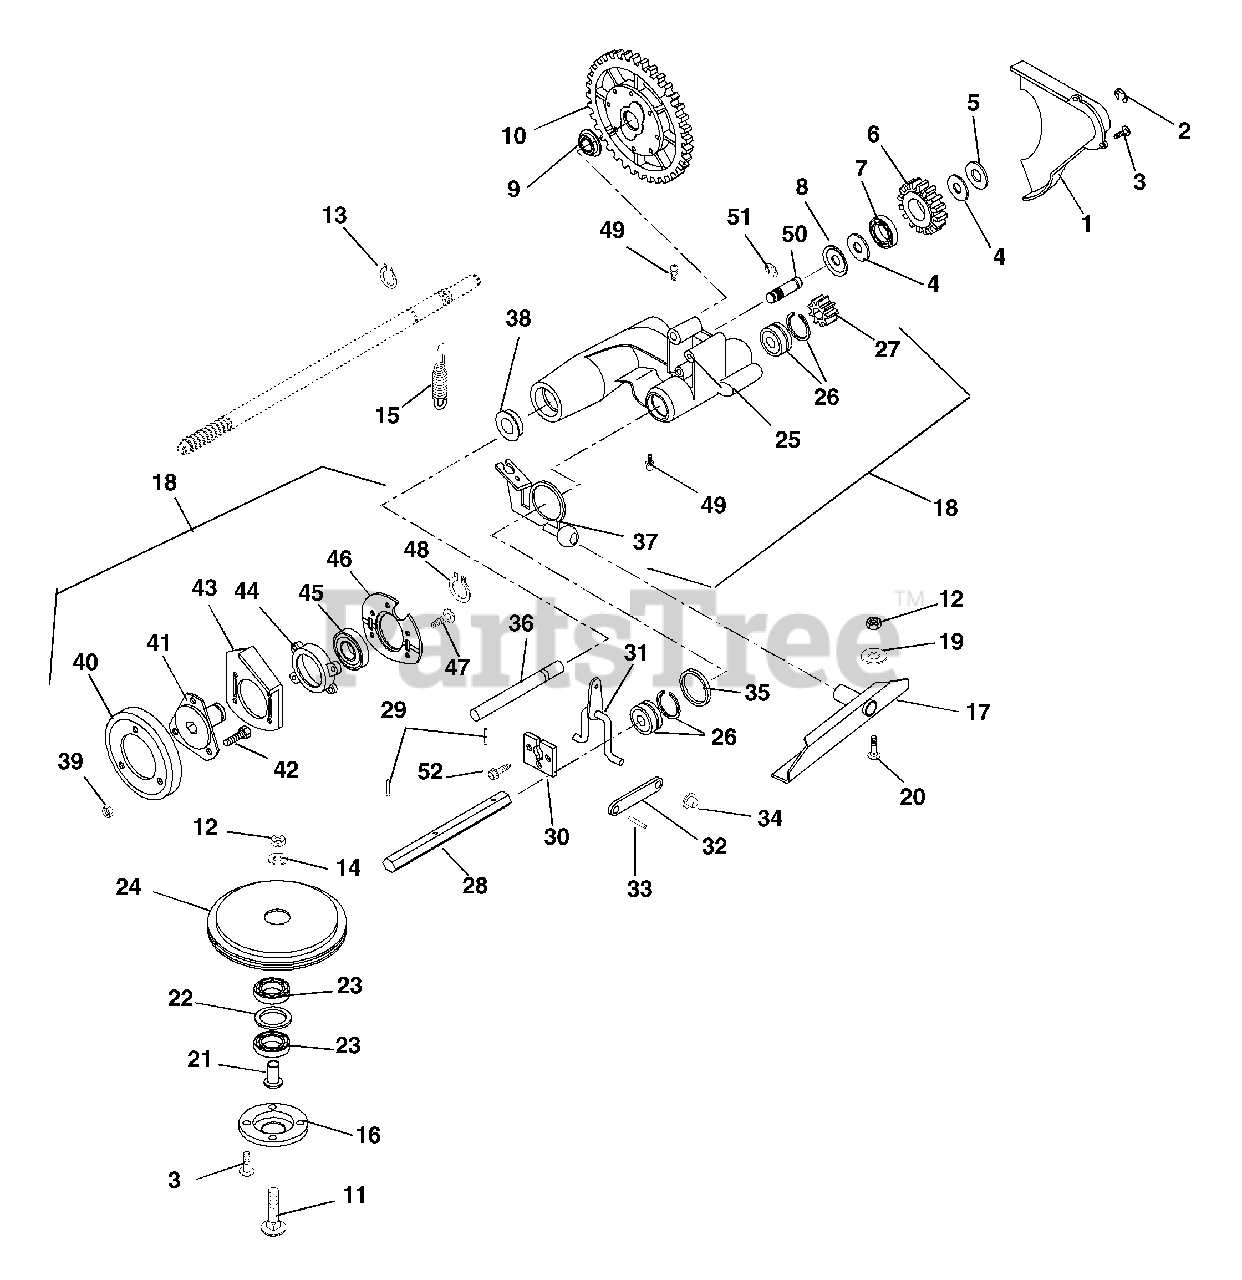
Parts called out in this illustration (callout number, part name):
1	Gear Cover
2	Ring-Retaining-External .438 x .035
3	Screw-Tapping 12-24 x .50 Hex Washer Head
4	Washer - Flat - Steel .520 x .827 x .062
5	Washer - Flat - Steel .531 x 1.00 x .063
6	Idler Gear
7	Bearing - Ball .50 x 1.38 x .437
8	Retainer
9	Bearing-Ball .625 x 1.38 x .50
10	Differential Assembly
11	Bolt-Round Head Square Neck .31-18 x 1.75 Grade 5
12	Nut-Locking-Center .31-18
13	Ring-Retaining-External .625 x 035
14	Washer-Flat-Steel .38 x .87 x .179
15	Spring-Tension .051 x .60 x 2.25
16	Bearing, Retainer
17	Pivot Channel Weldment
18	Kit, LM Drive Carrier
19	Washer-Flat-Steel .344 x .688 x .065
20	Bolt-Round Head Square Short Neck .31-18 x .62
21	Spindle, Bearing
22	Washer- Flat-Steel 1.062 x 1.344 x .032
23	Bearing-Ball .625 x 1.375 x .43
24	Friction Sheave
25	Drive Carrier
26	Bearing - Ball .562 x 1.375 x .437
27	Gear-Pinion
28	Hex Shaft
29	Pin - Roll .125 x .50
30	Retainer Plate
31	Shift Arm Weldment
32	Shift Link
33	Pin-Roll .125 x .63
34	Push Nut .25
35	Washer - Flat - Steel 1.390 x 2.00 x .020
36	Rod-Guide
37	Drive Actuator Weldment
38	Bearing-Ball .625 x 1.38 x .50
39	Nut-Locking-Center .25-20
40	Disc, Friction
41	Hub, Friction Wheel
42	Bolt-Hex .25-20 x .50 Grade 5
43	Bearing Plate
44	Bearing Retainer
45	Bearing Ball 1.00 x 2.00 x .56
46	Bearing Retainer
47	Screw-Hex Flange Washer Head Tapping 5MM-0.8 x 16MM
48	Ring-Retaining - External 1.00 x .042
49	Fitting-Lube .25-28 x .256
50	Idler Shaft
51	Ring-Retaining-External .438 x .035
52	Screw-Tapping 12-24 x .50 Hex Washer Head
